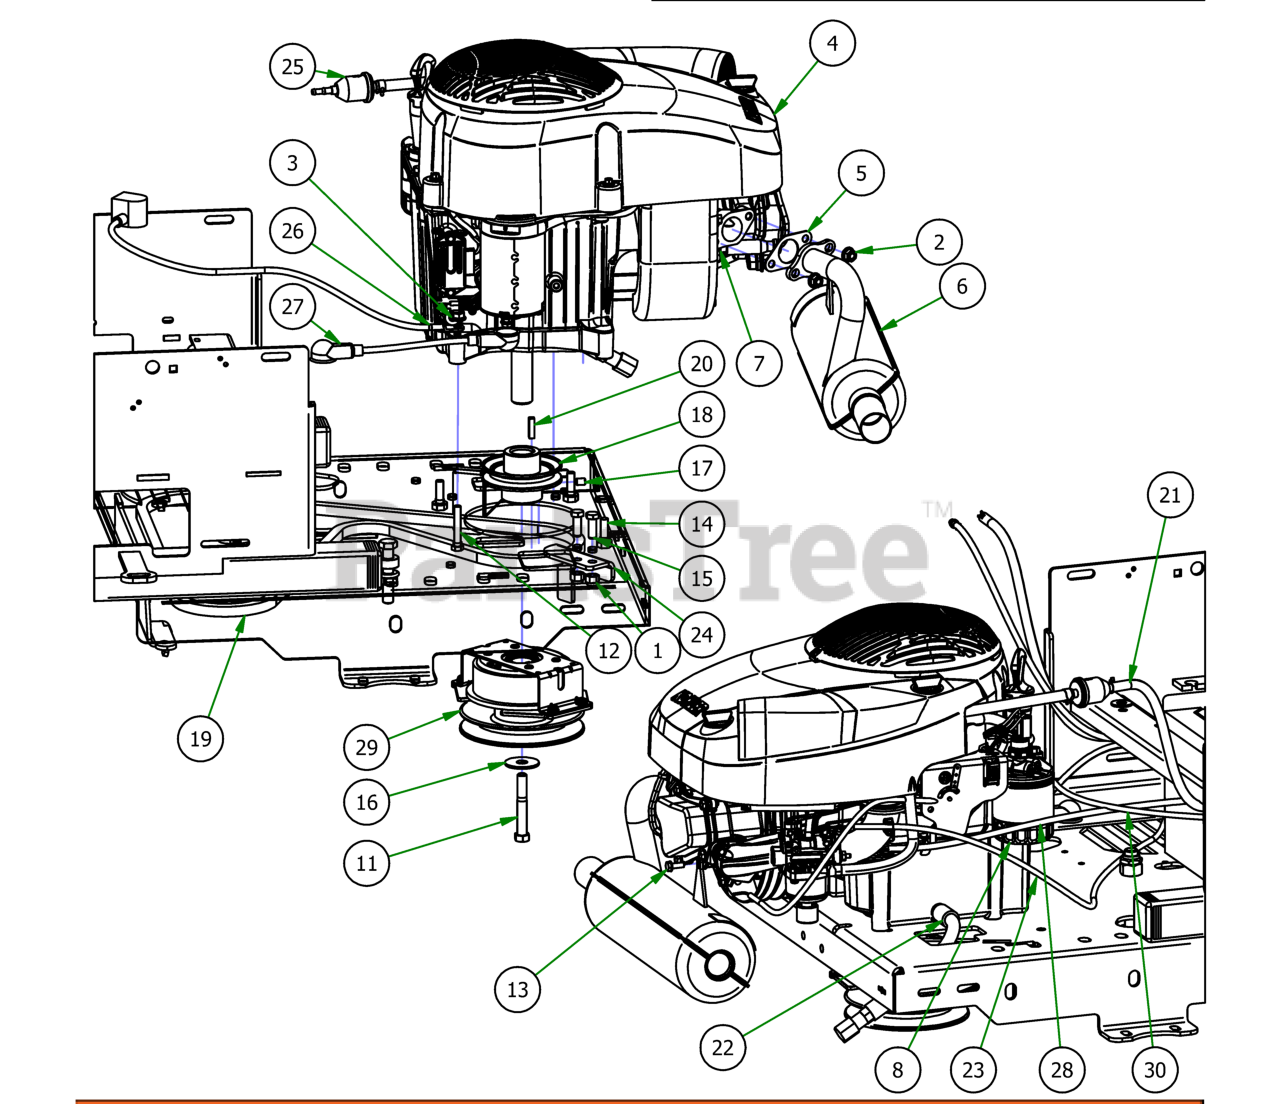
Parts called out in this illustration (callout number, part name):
1	3/8 Nylock Nut
2	M8 Nut Connects the 015-1012-00 and the 015-8240-00
3	5/16" Flange Nut
4	Kohler KS-590 541cc 19Hp
5	Exhaust Gasket
6	Kohler KS-590 Muffler
7	Kohler KS-590 Spark Plug
8	Kohler KS-590 Oil Filter
9	Kohler KS-590 Air Pre-Cleaner
10	Kohler KS-590 Air Filter
11	7/16"-20 x 3" Hex Bolt Gr. 8
12	5/16-18 X 2 Hex C/S (GR.5) ZC
13	M6-1.0x16mm Self-Tapping Bolt
14	3/8 x 1 1/8 bolt
15	3/8" x 1" Hex Bolt
16	Clutch Washer
17	3/8" Set Screw
18	3-3/4" Motor Pulley
20	1/4" x 1" Key
21	37" Fuel Line Assembly
22	Oil drain Hose
24	2017 MZ Clutch Stop
25	Universal In-line Fuel Filter
26	24 inch Black Cable – MZ/ZT
27	12" Red Battery Cable
28	MZ Kohler EPA Canister Assembly
30	2017 MZ Control Panel Assembly
